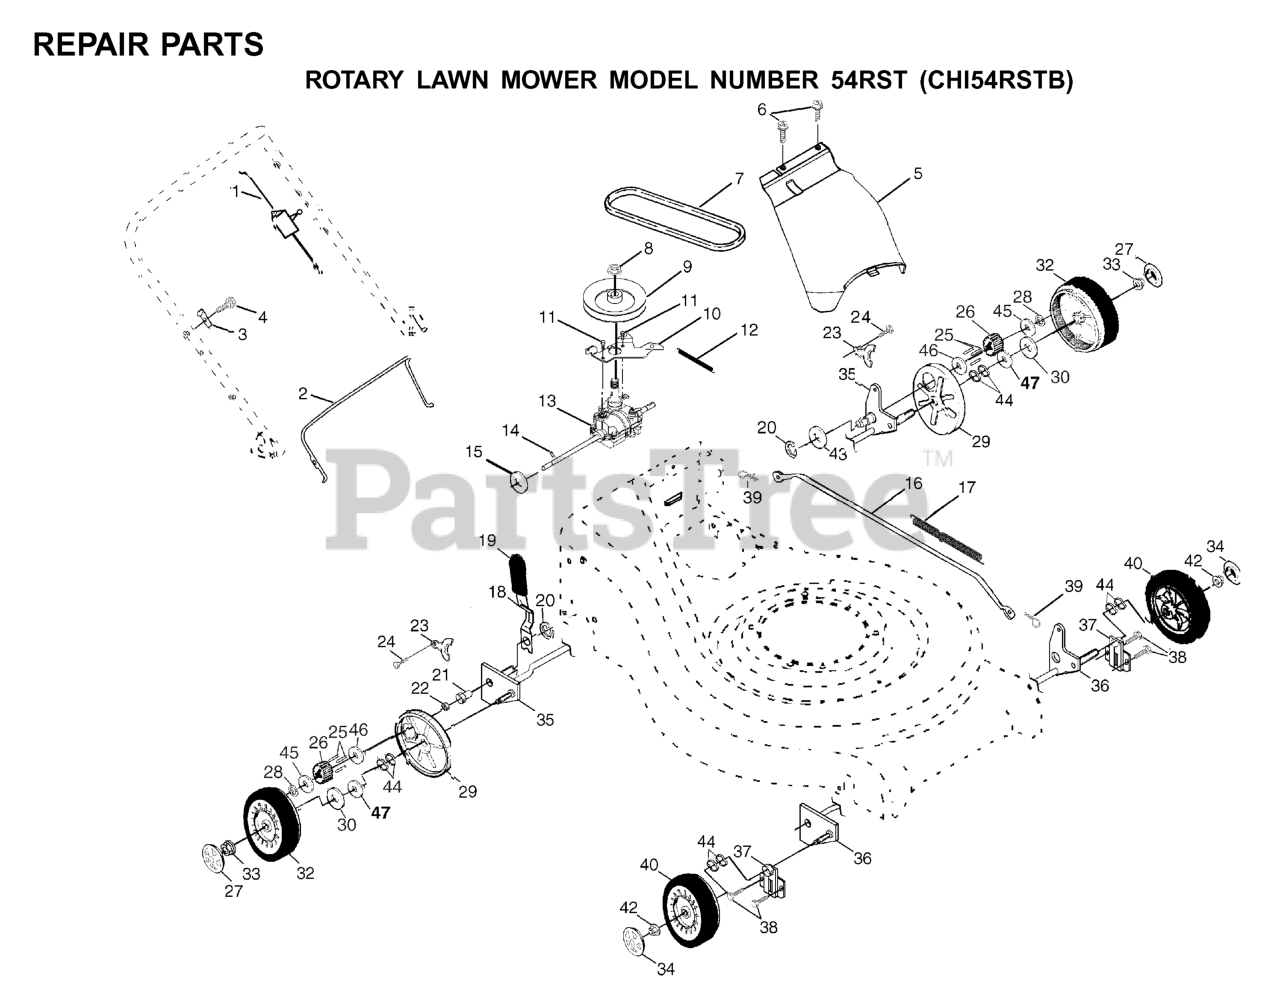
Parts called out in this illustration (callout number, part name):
1	CABLE.DRIVE.21.RWGD.
2	BAIL.CONT.DR.21.RWGD.BLACK
3	DOWNSTOP BRACKET
4	SCREW.HEX.HEAD.WASHER.10-16
5	DRIVE COVER
8	FLANGED LOCKNUT 3/8-16 ZINC
10	BELT GUIDE
11	Screw, Hex Washer Head #10-24 x .668
13	TRANSMISSION ASM. (WALK)
14	PIN.SPRING.THRUST
15	THRUST WASHER
16	ROD CONNECTING
17	SPRING
18	SPRING
19	KNOB
21	RP BEARING SUPPORT
22	BEARING, BALL
23	BRACKET
25	PAWL.DRIVE.ETCHED
26	PINION.DRIVE.WALK
27	CAP.HUB.ARC.SPOKE.8".LP
28	E-RING 7/16 RE
29	DUST SHROUD PM
30	WASHER FLUT
33	HEX FLANGE LOCKNT
34	CAP.HUB.ARC.SPOKE.8".LP
35	SHAFT ASSY
36	SHAFT ASSY
37	RETAINER.FRONT.SHAFT
39	RETAINER CLIP
40	WHEEL ASMBLY FRONT
42	HEX FLANGE LOCKNT
43	WASHER.ZINC.PLATED
44	WAVE WASHER
46	WASHER.BELLEVILLE (3 2 LB)
